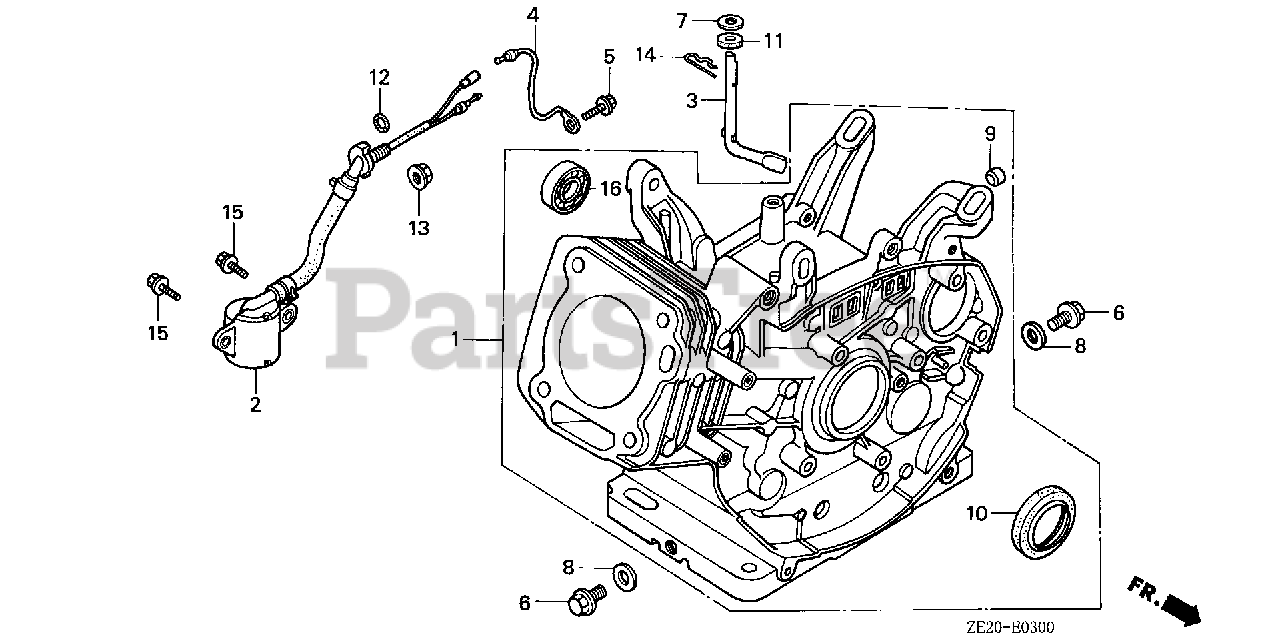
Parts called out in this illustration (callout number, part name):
1	CYLINDER ASSY. (STD)
3	SHAFT, GOVERNOR ARM
6	BOLT, DRAIN PLUG (12X15)
7	WASHER (8.2X17X0.8)
8	WASHER, DRAIN PLUG (12MM)
9	PLUG, SEALING (RUBBER 10MM)
10	OIL SEAL (30X46X8)
11	OIL SEAL (8X14X5)
14	PIN, LOCK (8MM)
